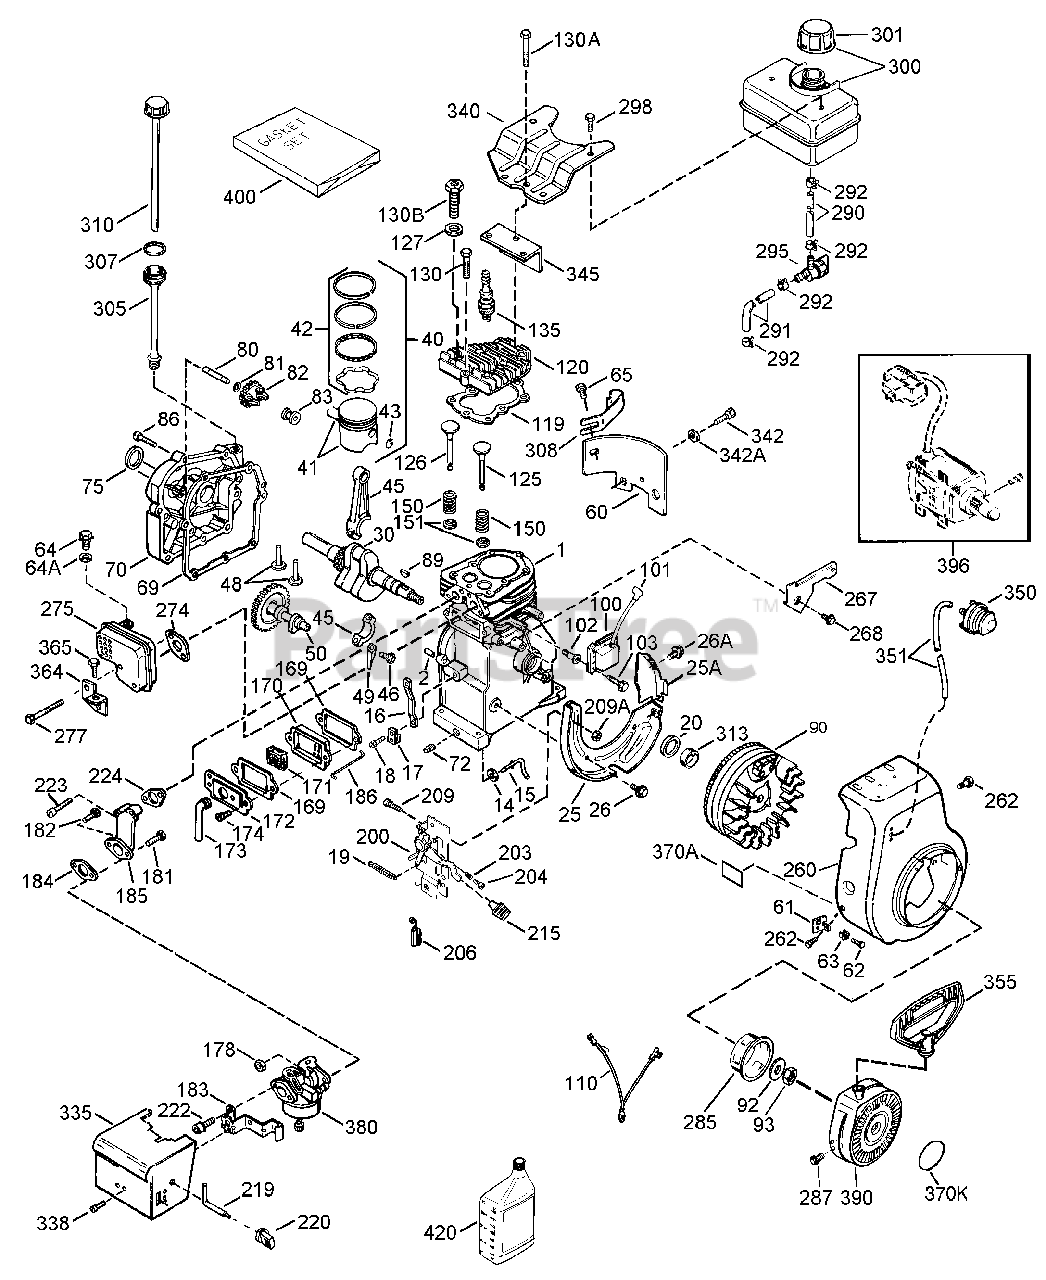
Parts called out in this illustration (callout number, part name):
1	Cylinder Assembly (Incl. Ref. #2, 20, 72 & 125)
2	Dowel Pin
15	Rod-Governor
16	Lever-Governor
17	Clamp, Governor
19	Spring-Extension
20	&al, Oil
25	Baffle-Blower Housing
25A	Extension-Baffle
30	Crankshaft Assy.
40	Set-Piston, Pin & Ring (Std)
41	Piston & Pin Asm.. Standard (Incl. Ref. #43)
42	Ring Set (Std.)
43	Ring-Retaining
45	Connecting Rod Assembly (Incl. Ref. #46 & 49)
48	Lifter Valve
49	Dipper-Oil
50	Camshaft
60	Extension-Blower
61	Bracket
63	Grommet
64A	Washer
69	Gasket-Cylinder Cover
70	Cover-Cylinder (Incl. Ref. #75 & 80)
72	Plug-Pipe
75	Oil Seal
80	Governor Shaft
82	Gear-Governor (Incl. Ref. #81)
83	Spool-Govemor
89	Key Flywheel
90	Flywheel-w/Ring Gear
93	Flywheel Nut
100	Solid State
101	Cover Spark Plug
110	Wire-Ground
119	Gasket-Cylinder Head
120	Head-Cylinder (Incl. Ref. #131)
125	Valve-Exhaust Standard (Incl. Ref. #151)
126	Valve-Intake Standard (Incl. Ref. #151)
135	Spark Plug (RJ19LM)
150	Spring Valve
151	Cap-Valve Spring
169	Gasket-Valve Cover
170	Body-Valve Cover
171	Element Breather
172	Cover-Breather
173	Breather Tube
181	Screw-Hex Hd.
182	Screw
183	Bracket-Choke
184	Gasket-Carburetor
185	Pipe-Intake
186	Link-Governor to Throttle
200	Control Assembly (Incl. Ref.# 203, 204, 206, 209 & 209A)
206	Terminal
215	Choke Knob
219	Rod-Choke
220	Choke Knob
223	Screw-Fil Hd.
224	Gasket-Intake
260	Housing-Blower
267	Bracket-Hold Down
274	Gasket-Exhaust
275	Muffler (Incl. Ref.# 274)
277	Screw-Fil. Hd.
285	Cup-Starter
290	Fuel Line
291	Fuel Line
292	Clamp Fuel Line
295	Valve-Shut Off
300	Tank Assembly-Fuel (Incl. Ref. #292 & 301)
301	Cap Fuel
305	Oil Fill Tube
310	Dipstick
335	Cover-Carburetor
340	Plate-Fuel Tank
345	Baffle-Heat
350	Primer-Asm
351	Line-Primer
355	Handle-Starter
364	Bracket-Carburetor Cover
370A	Decal-Instruction
370K	Emblem Decal
380	Carburetor (Incl. Ref. #184)
390	Rewind Starter
396	Motor-Electric Starter
400	Gasket Set
420	Oil-Engine (SAE 5W30)
